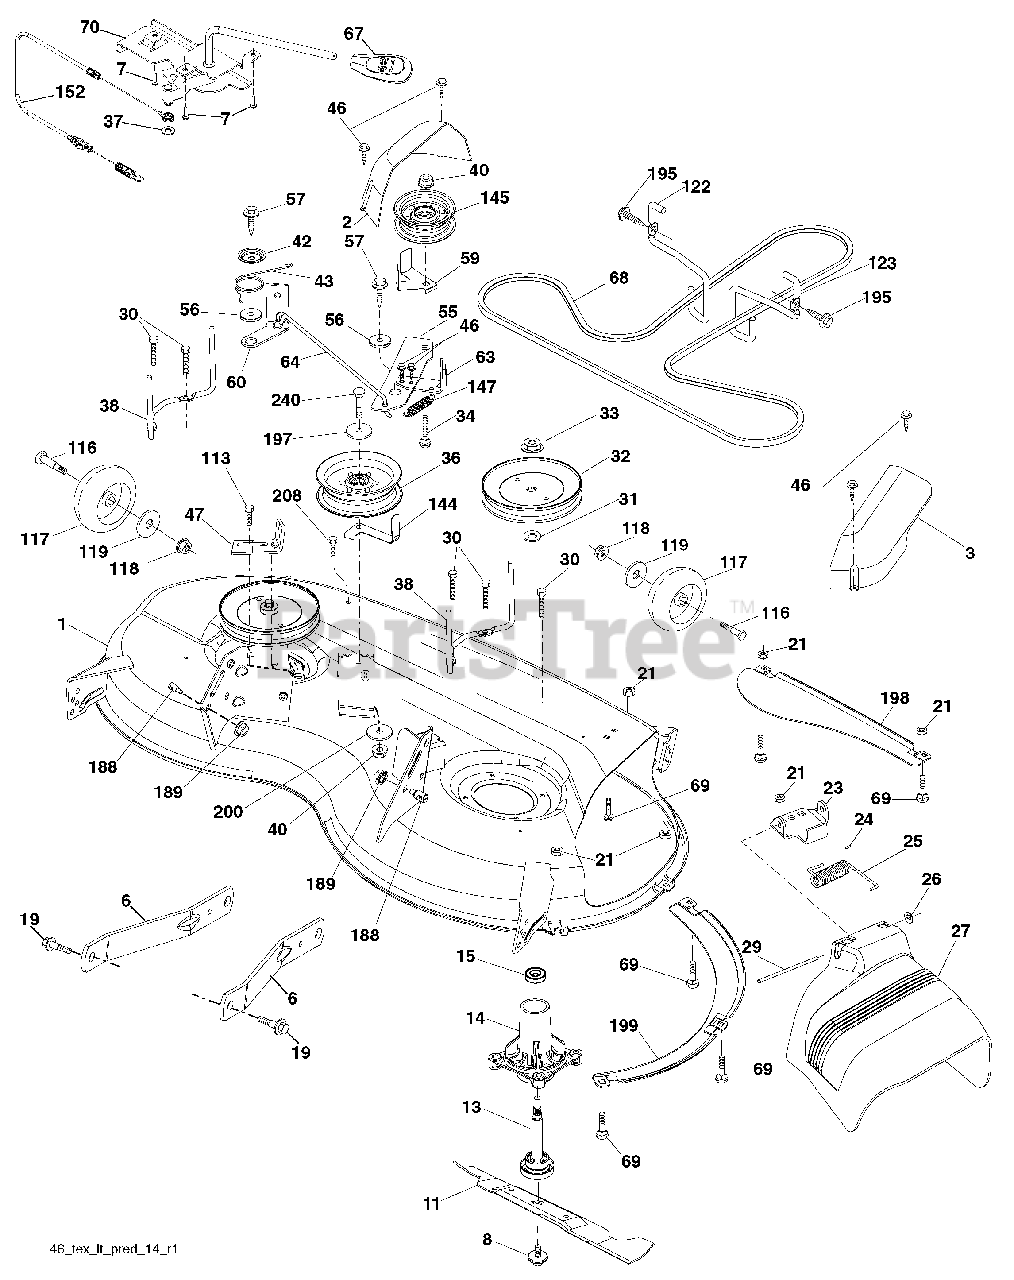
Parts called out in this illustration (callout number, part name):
2	Cover Mandrel LH
3	Cover Mandrel RH
6	Arm Suspension
7	Screw #10 x 0.750 BOS Thread
8	Bolt/Washer Asm 7/16-20 unf
11	Blade Mower
13	Shaft Assembly, Mandrel
14	Housing, Mandrel
15	Bearing, Ball, Mandrel
19	Bolt, Shoulder
21	Nut
23	Bracket, Deflector
24	Cap, Sleeve
25	Spring, Torsion, Deflector
26	Nut, Push
27	Shield, Deflector
29	Rod, Hinge
30	Screw Thdrol Rolling Wsh Hd
31	Washer, Spacer
32	Pulley, Mandrel
33	Nut, Toplock, Flanged
34	Bolt Carr Sh. 3/8-16 x 1-1/2 Gr. 5
36	Pulley, Idler
37	Washer 13/32 x 13/16 x 16 Ga.
38	Keeper Belt LH Mandrel
40	Nut, Lock Flg. 3/8-16 unc
42	Spring Torsion Brake
43	Spring Torsion Retainer
46	Screw
47	Bracket Clutch Cable
55	Arm, Idler
56	Spacer, Retainer
57	Screw Hexwsh Thd 3/8-16 x 1
59	Guard, Tuv Idler (94)
60	Arm Brake Mower
63	Arm Brake Mower
64	Linkage Brake
67	Handle, Clutch Cable
68	V-Belt
69	Bolt
70	Clutch Asm. Manual
113	Screw 5/16-18
116	Bolt, Shoulder
117	Wheel, Gauge
118	Nut, Crownlock 3/8-1
119	Washer 13/32 x 7/8 x 14 Ga.
122	Keeper Belt Eng. LH
123	Keeper Belt Eng. RH
144	Keeper Belt
145	Pulley Idler Primary
147	Spring Return
152	Cable Clutch Manual w/Spr.
188	Stud Fastener
189	Nut Lock Hex Flange
195	Screw 3/8-16 x 3/4
197	Washer 13/32 x 13/16 x 12 Ga.
198	Baffle Center Front
199	Baffle Front RH
200	Washer 13/32 x 1 x 1/2 11 Ga.
208	Screw Thdrol 3/8-16 x 1/2
240	Bolt Fin Hex 3/8-16 x 2-1/4 Gr. 5
240	Mandrel Assembly
240	Replacement Mower, Complete
